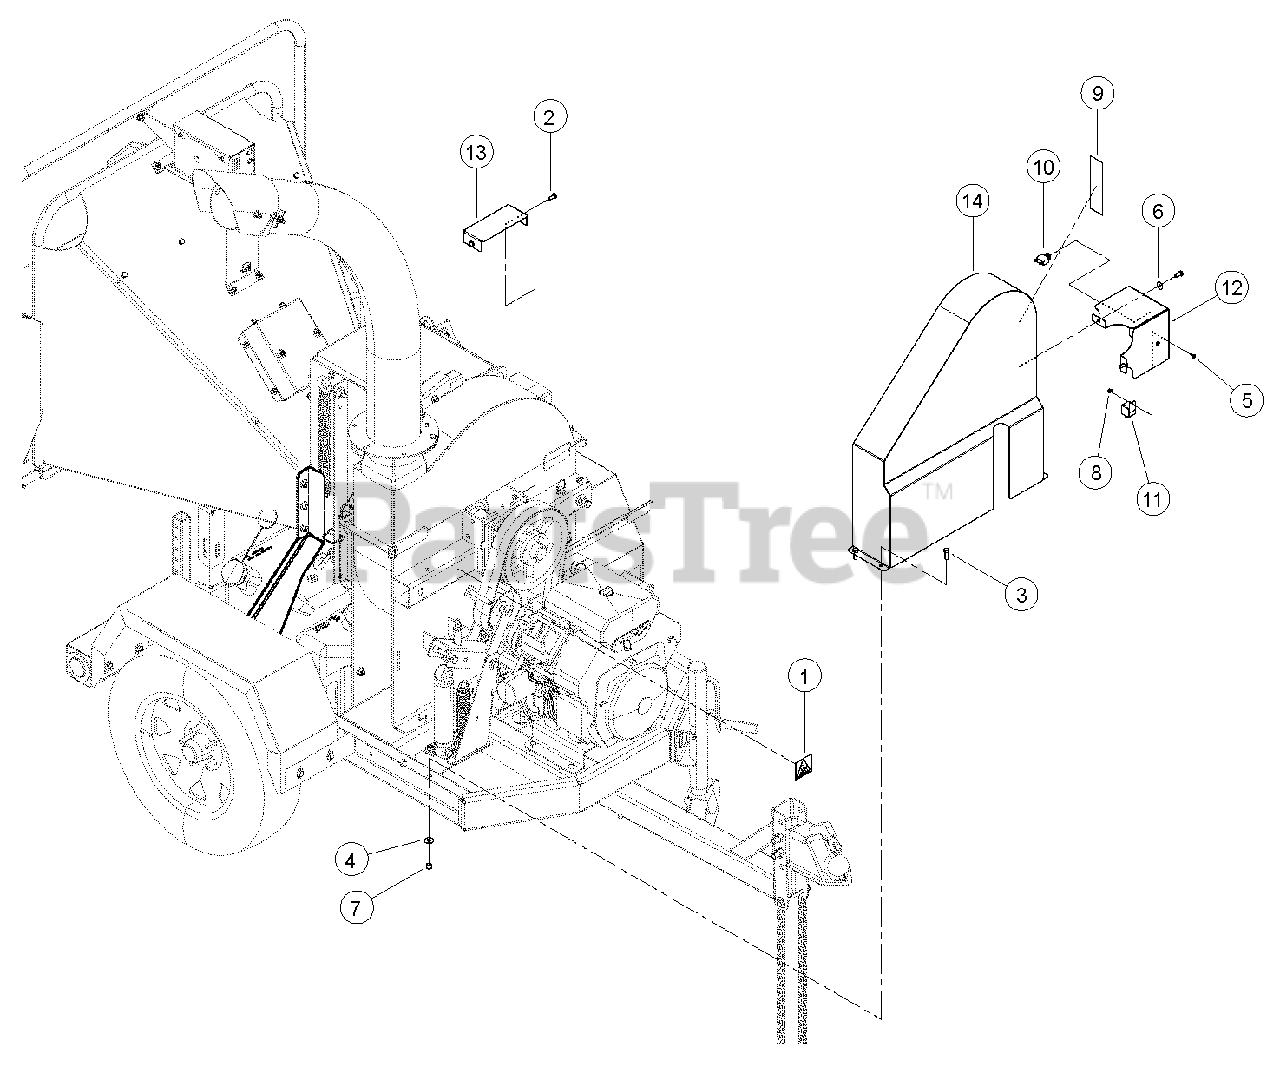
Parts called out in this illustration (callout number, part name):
1	DECAL, SHIELD DANGER ISO
2	BOLT, 5/16 X 3/4 HEX HD
3	BOLT, 3/8 NC X 1 HEX HD GR5 ZP
4	WASHER, 3/8 FLAT ZP
5	SCREW, #10 X 1/2 HWH TEK ZP
6	WASHER, 5/16 FLAT ZP
7	NUT, 3/8 NYLOCK
8	NUT, NO. 10 X 24 NYLOCK
9	DECAL, CHIPPER ENGAGEMENT
10	CIRCUIT BREAKER, 10 AMP RESETTABLE
11	RELAY, 12V SPDT W/ FLANGE
12	COVER, CHIPPER VALVE
13	COVER, CHIPPER SHAFT
14	WELDMENT, BELT SHIELD
